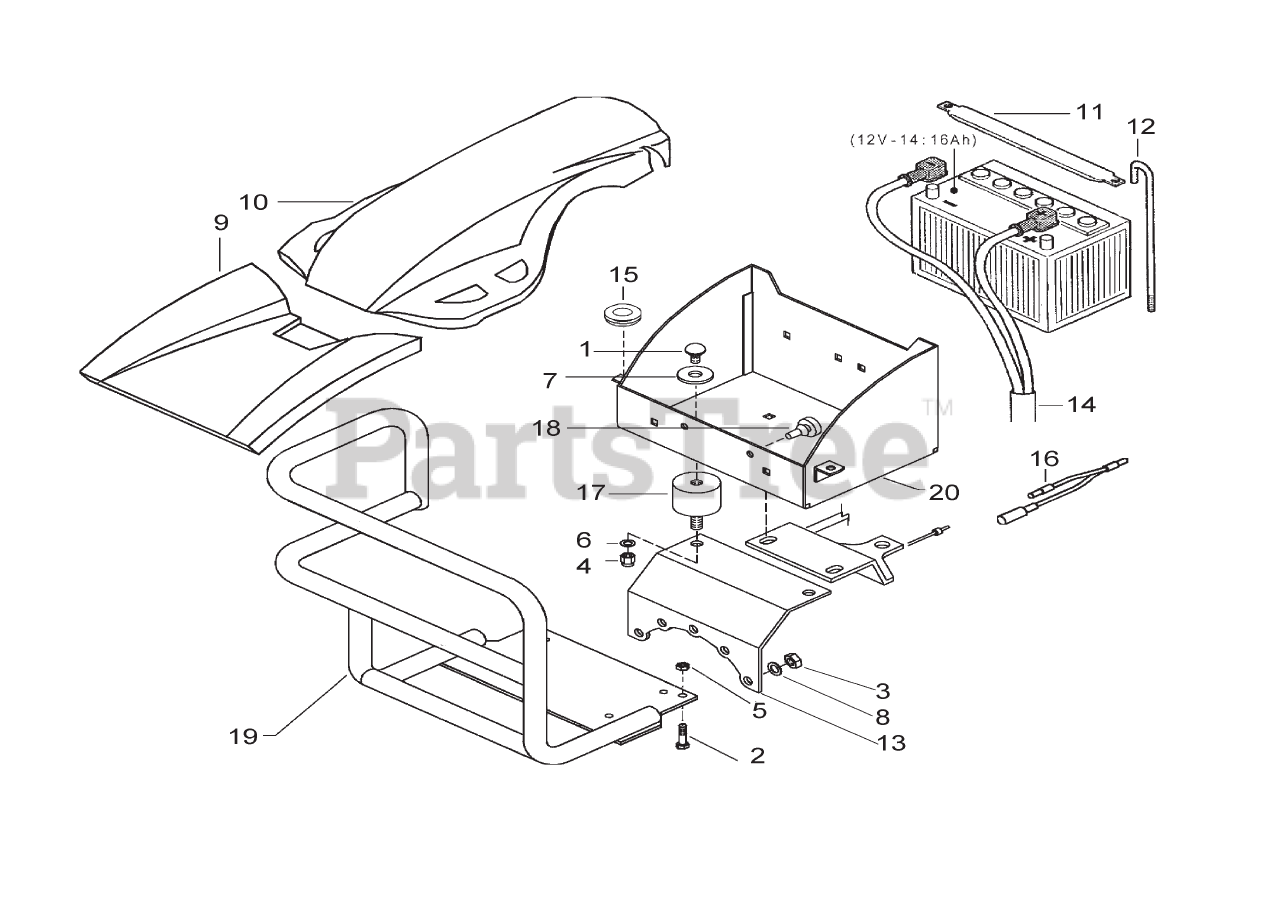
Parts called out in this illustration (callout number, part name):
1	BOLT, M6X12
2	CAP SCREW, M8X40
3	NUT M8
4	NUT, LOCK, M6
5	NUT, LOCK, FLANGED, M8
6	WASHER, FLAT, M6
7	WASHER, FLAT, M9X24
8	WASHER, LOCK, M8.4
9	GUARD, LOWER
10	GUARD, STEERING COLUMN
11	BATTERY BRACKET
13	SUPPORT, BATTERY/ COVER
14	CABLE, ELECTRIC STARTER
15	SUPPORT, BODY GUARD
16	WIRE HARNESS
17	RUBBER MOUNT
18	BUMPER
19	BUMPER, GX390
20A	BATTERY BOX, ELECTRIC START
20B	COVER SUPPORT, RECOIL START
